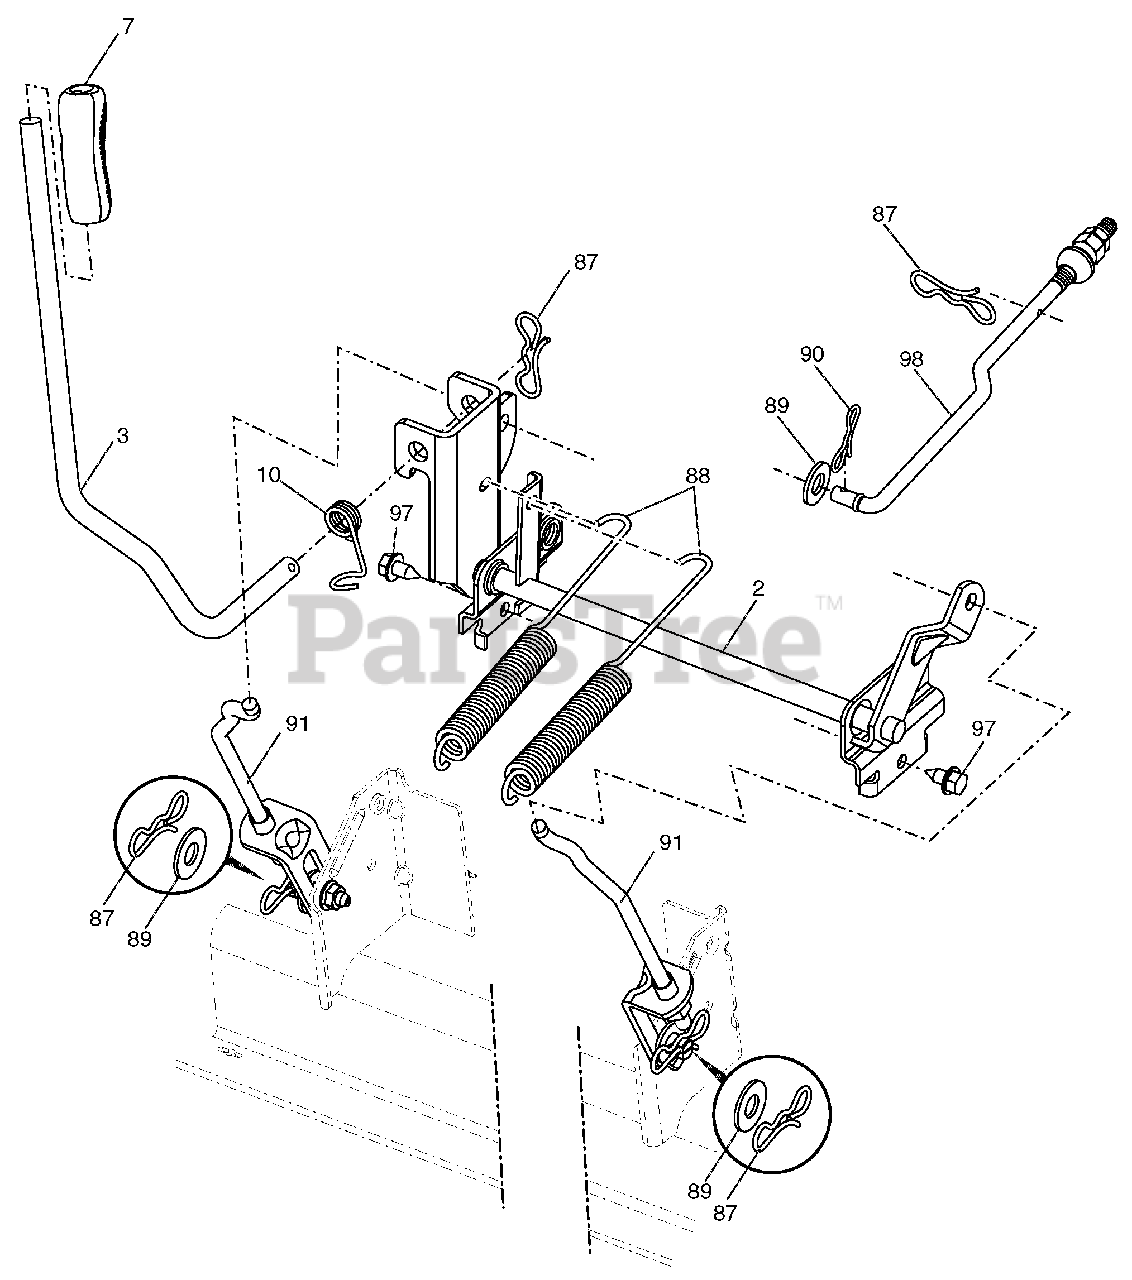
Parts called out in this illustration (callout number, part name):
2	SHAFT ASM., LIFT
3	LEVER ASM., LIFT RH
7	GRIP LEVER 5625 LD BLACK 428
10	SPRING.TORSION.HANDLE.LIFT
87	PIN.COTTER.7/16.BOW TIE LOCK
88	SPRING LIFT ASSIST
89	WASHER.CLEAR ZINC
90	PIN.COTTER.5/16.BOW TIE LOCK
91	LINK ASM.LIFT.54"TG
97	SCREW.HEXWSH THDR3/8-16X3/4.BL
98	LINK ASM.SUSP.FRONT.MWR.10.5
